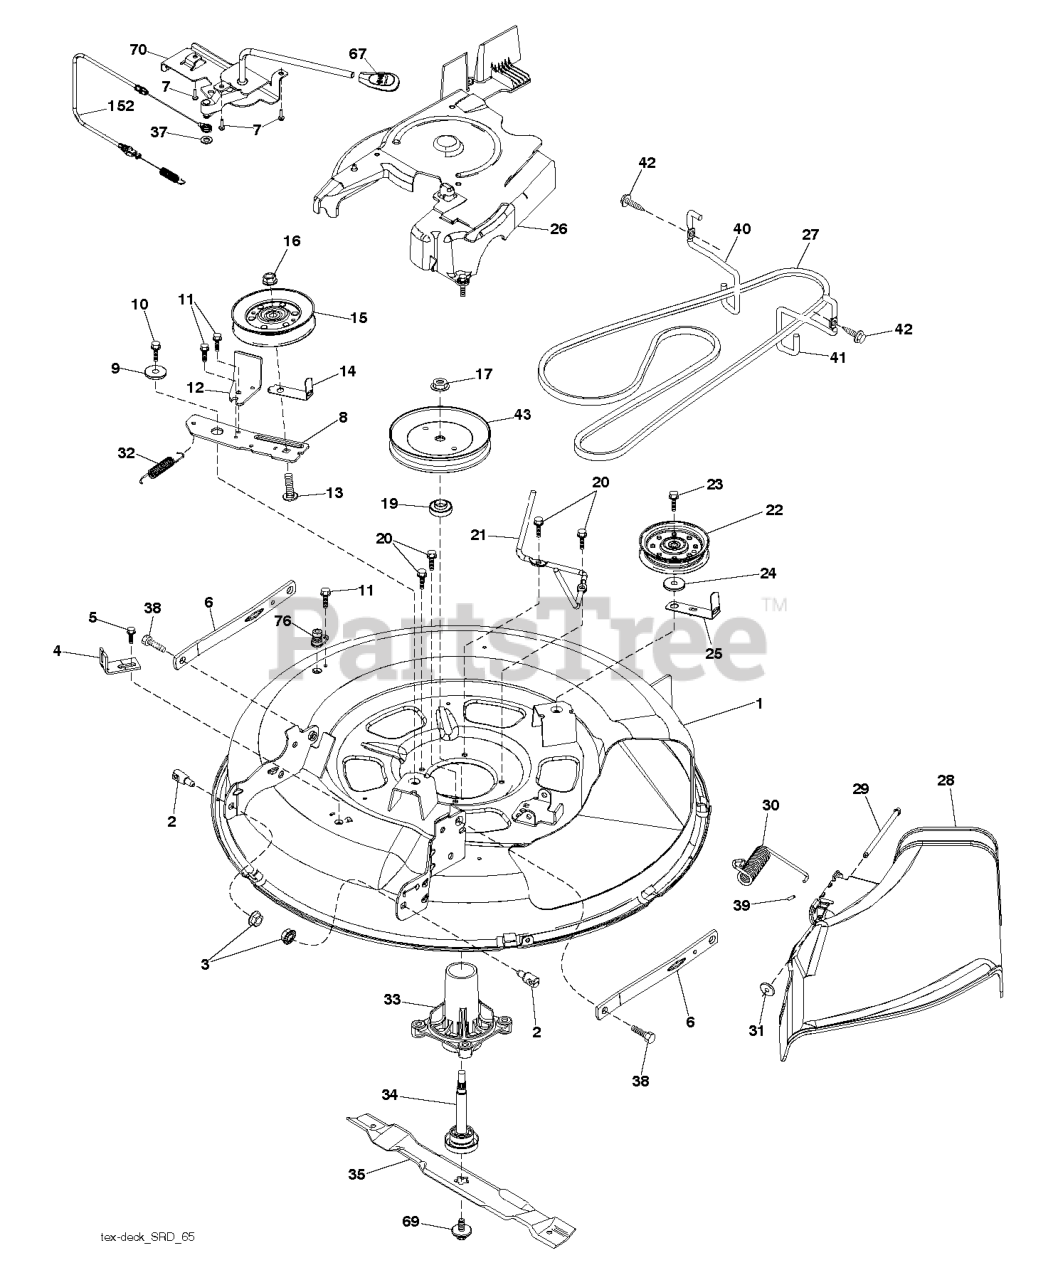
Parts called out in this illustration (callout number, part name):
1	WHEEL.STEER.HUSQ.SR.498.OVMLD
2	AXLE.CAST.IRON
4	SPINDLE.WELDED.LH.16"TEX
5	SPINDLE.WELDED.RH.16"TEX
6	WASHER THRUST
9	CAP.SPINDLE.BLACK
15	NUT CROWNLOCK 3/8-24
16	SHAFT.STEER.2HIGH.SPLND.PLATED
19	PLATE.STEER.DDL.NLT/NG
21	ADAPTER.WHEEL.STEER.SPLND.ALUM
22	BEARING.SUBASM.SHAFT.STEER.LOW
26	INSERT.CAP.WHL.STRG.HUSQ.PREM
28	SCREW, 3/8-16X3/4
35	GEAR.SECTOR.PLATE.DDL.
45	WASHER.3/8ID.2-3/8OD.12GA.PLTD
50	NUT LOCK FLG 3/8-16 UNC
53	WASHER.HARDENED
55	SPACER.BRACE.AXLE
58	BOLT.SHOULDER.SECTOR.P
59	WASHER.THURST.SECTOR.S
60	NUT FLANGE LOCK 5/8-11
61	Links
62	Links
63	SCREW
64	RETAINER.CLIP.SPRING.S
65	BRACE.AXLE.FRONT.NLT/N
66	BOLT HEX FGHD 7/16-14 X 3 SERR
67	BUSHING.PM.FRONT AXLE
68	NUT.LOCK.FLANGE.7/16
69	WASHER.1.5X.505X.118
70	BRACKET.FRT.DECK.SUSP.RR.MT431
75	PINION.ZINC PLATED
76	SCREW HEAD SOCKET LRVB
78	THRUST WASHER
122	CAP.GEAR.SECTOR.TEX
